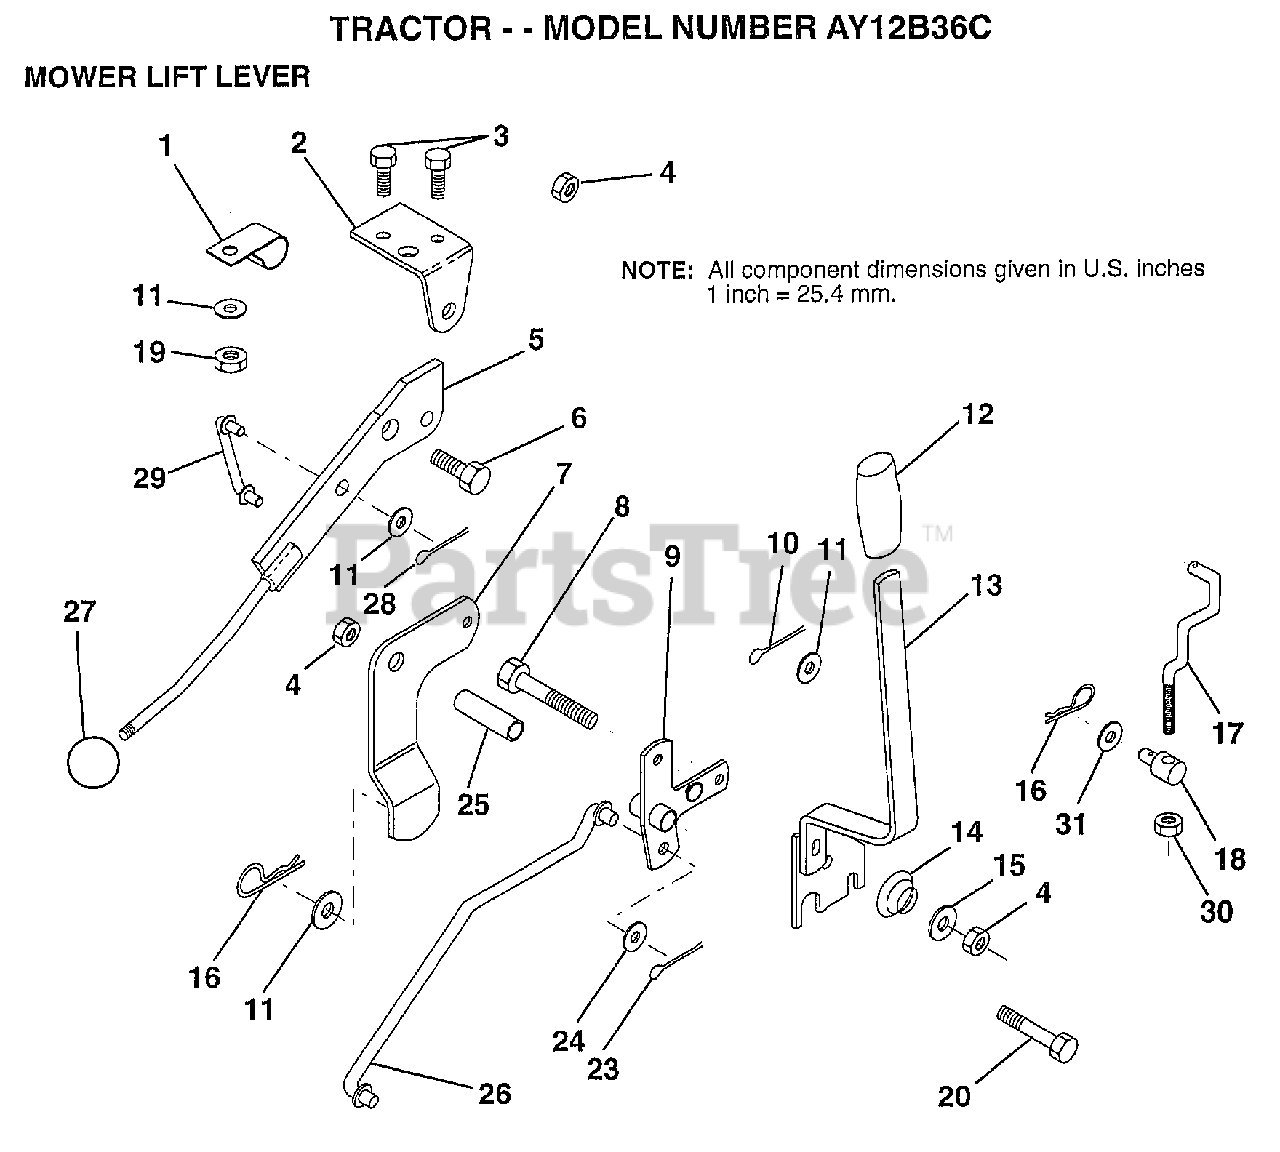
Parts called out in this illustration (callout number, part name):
1	"CLIP,INSULATOR"
2	BRKT CLUTCH
3	BOLT HXHD FIN
5	LEVER.ASM.CLUTCH
6	"BOLT, SHOULDER LT"
7	MWR CLUTCH ARM AS
8	BOLT
9	"BELLCRANK,LIFT"
10	COTTER PIN
11	WASHER
13	HANDLE.ASM.LIFT
14	SPRING COMPRESSIO
15	WASHER T
16	SPRING.RETAINER
17	"LINK,LIFT FRT"
18	TRUNION ADJ
19	NUT HXKEP 1/4X20
20	BOLT
23	PIN COTTER 1/8
25	TUBE SPACER
26	ROD LIFT MOWER
27	KNOB T(3/8 HOLE)
29	CLUTCH LINK
30	NUT
31	WASHER
